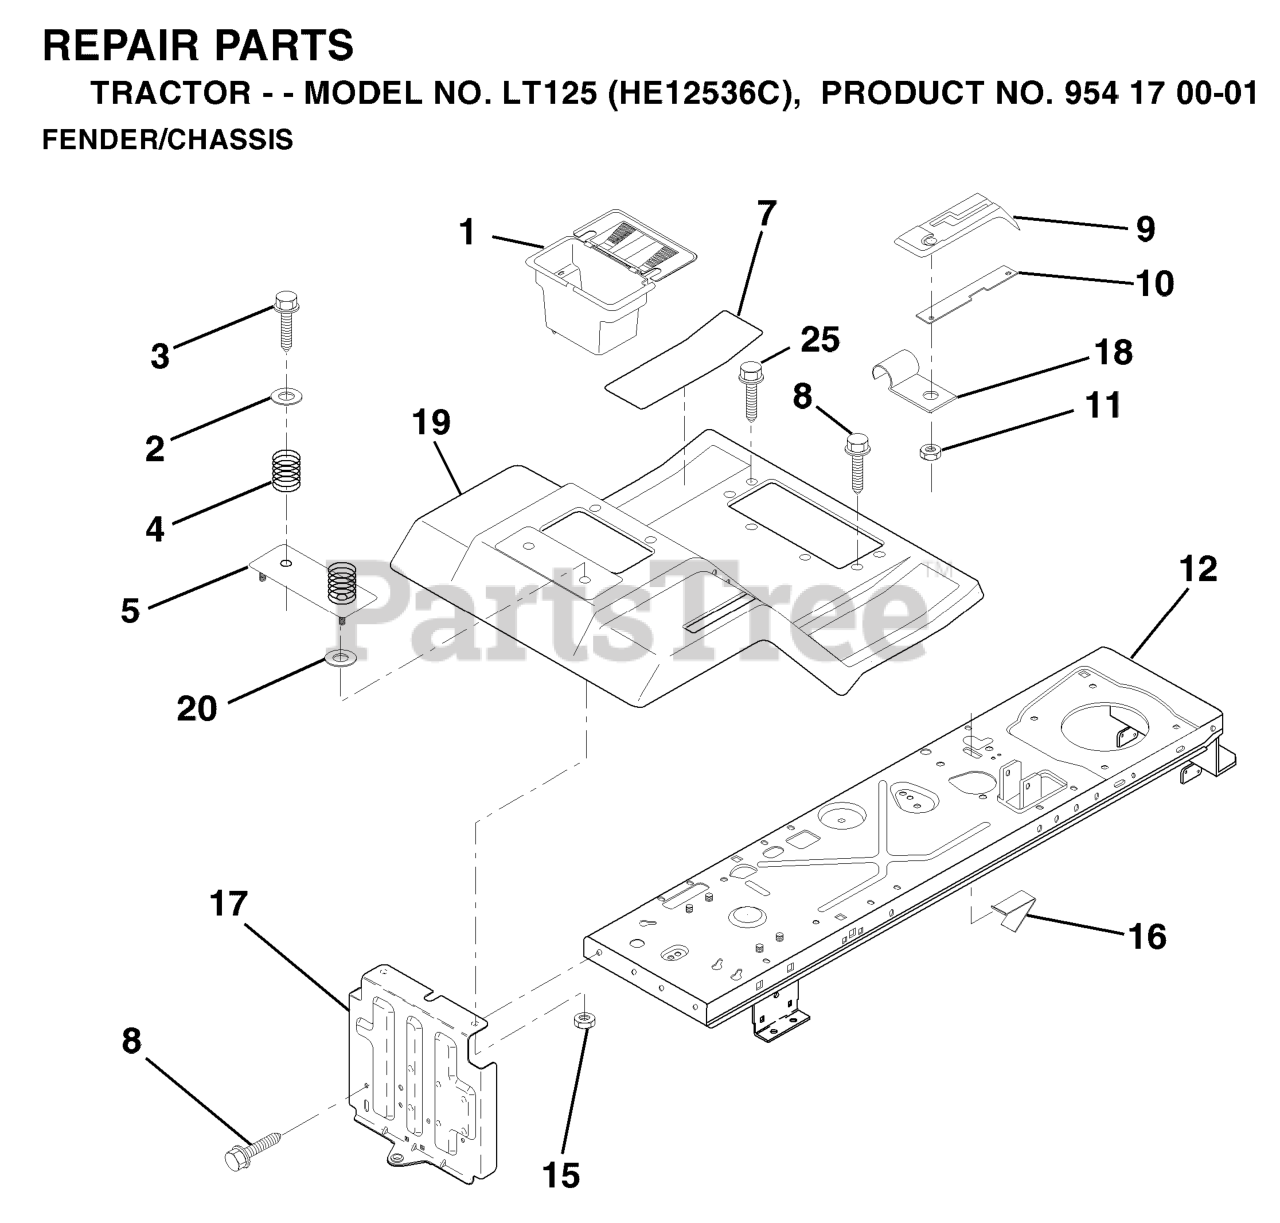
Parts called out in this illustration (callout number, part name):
1	CASE BATTERY MECH HINGE
2	WASHER
3	SCREW
4	SPRING COMPRESSION
5	PLATE ASM BATTERY
7	PAD FOOTREST
8	SCREW.THDROL.5/16-18X3/4.TTY
10	BAR, SHIFT LOCK
11	NUT.PUSH.3/16
15	Nut, Keps Blk Hex 1/4-20 UNC
16	SWITCH ACTUATOR
18	CLIP,INSULATOR
19	FENDER/FOOTREST
20	WASHER
25	Screw Hex Wsh Thdroll 5/16-18 x 1
